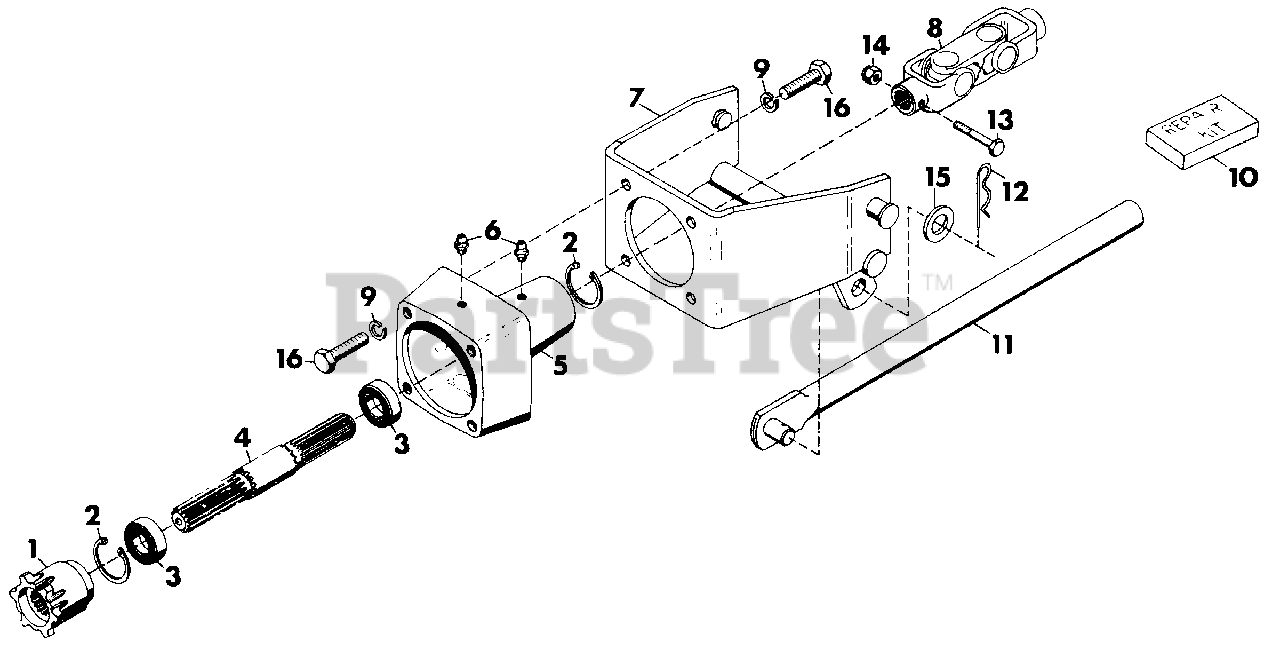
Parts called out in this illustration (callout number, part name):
1	DOG, ATTACHMENT
2	RING, RETAINING 2.062 BORE
3	BEARING, BALL .984X2.047X.590
4	SHAFT, FRONT ADAPTOR
5	HOUSING, ADAPTOR
6	FITTING, LUBE 1/4-28
7	WELDMENT, ADAPTOR
8	ASSEMBLY, DOUBLE JOINT
9	WASHER, LOCK 1/2 REGULAR
10	KIT, REPAIR U-JOINT ROCKWELL STD.
10	KIT, REPAIR U-JOINT NEAPCO 1605X
11	WELDMENT, PUSH ROD
12	PIN, HAIR
13	BOLT, HEX 1/4-20X2
14	NUT, LOCK 1/4-20
15	WASHER, FLAT .812X1.496X.134
16	BOLT, HEX 1/2-13X1.50
NS	DECAL, AMERICA
